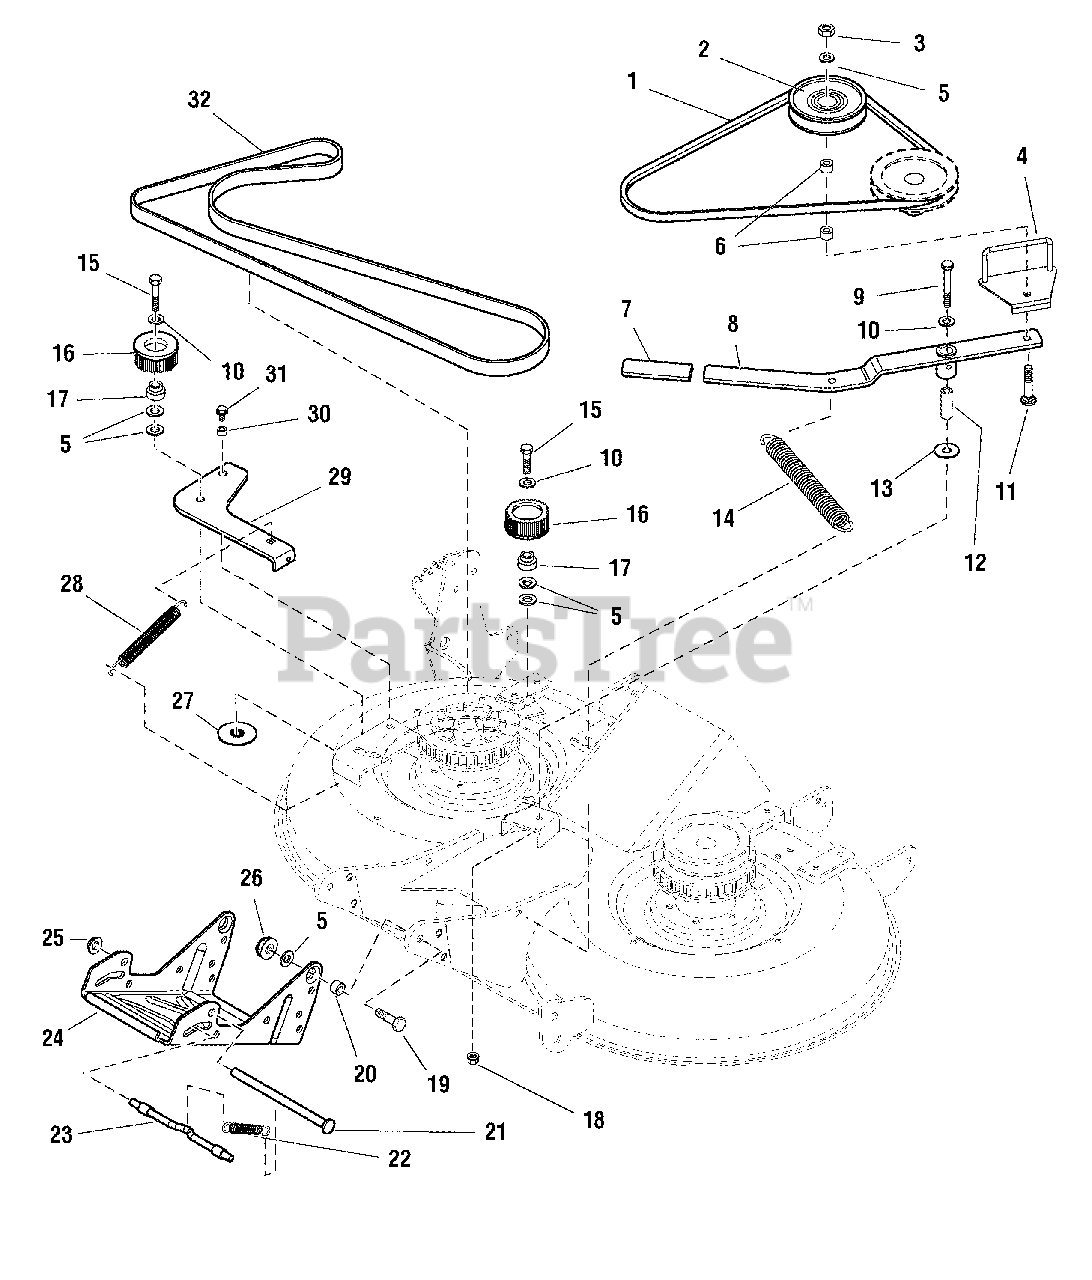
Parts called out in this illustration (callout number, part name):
2	PULLEY, 4-1/2 OD
3	NUT, Hex Lock ESNA, 3/8-16
4	PLATE & GUIDE ASEMBLY, Belt
5	WASHER
6	SPACER
7	GRIP, Black
8	IDLER ARM ASSEMBLY, w/Bushings
9	CAPSCREW, Hex Head, 3/8-16 x 3, G8
10	WASHER
11	CARRIAGE BOLT, 3/8-16 x 2-1/2
12	SPACER
13	WASHER
14	SPRING, Extension
15	CAPSCREW, Hex Head, 3/8-16 x 2
16	PULLEY, Idler
17	HUB, Pulley
18	NUT, Hex Flange Lock, 3/8-16
19	CAPSCREW, Hex Head, 3/8-16 1-3/8
20	SPACER
21	ROD
22	SPRING
23	ROD
24	HITCH, Mower
25	NUT, Push
26	NUT, Spiral Flange Toplock, 3/8-16
27	WASHER & LOCK NUT ASSEMBLY, 3/8-16
28	SPRING, Extension
29	ARM, Idler
30	SPACER
31	SCREW, Hex Head Taptite, 5/16-18 x 5/8
32	BELT, Timing
